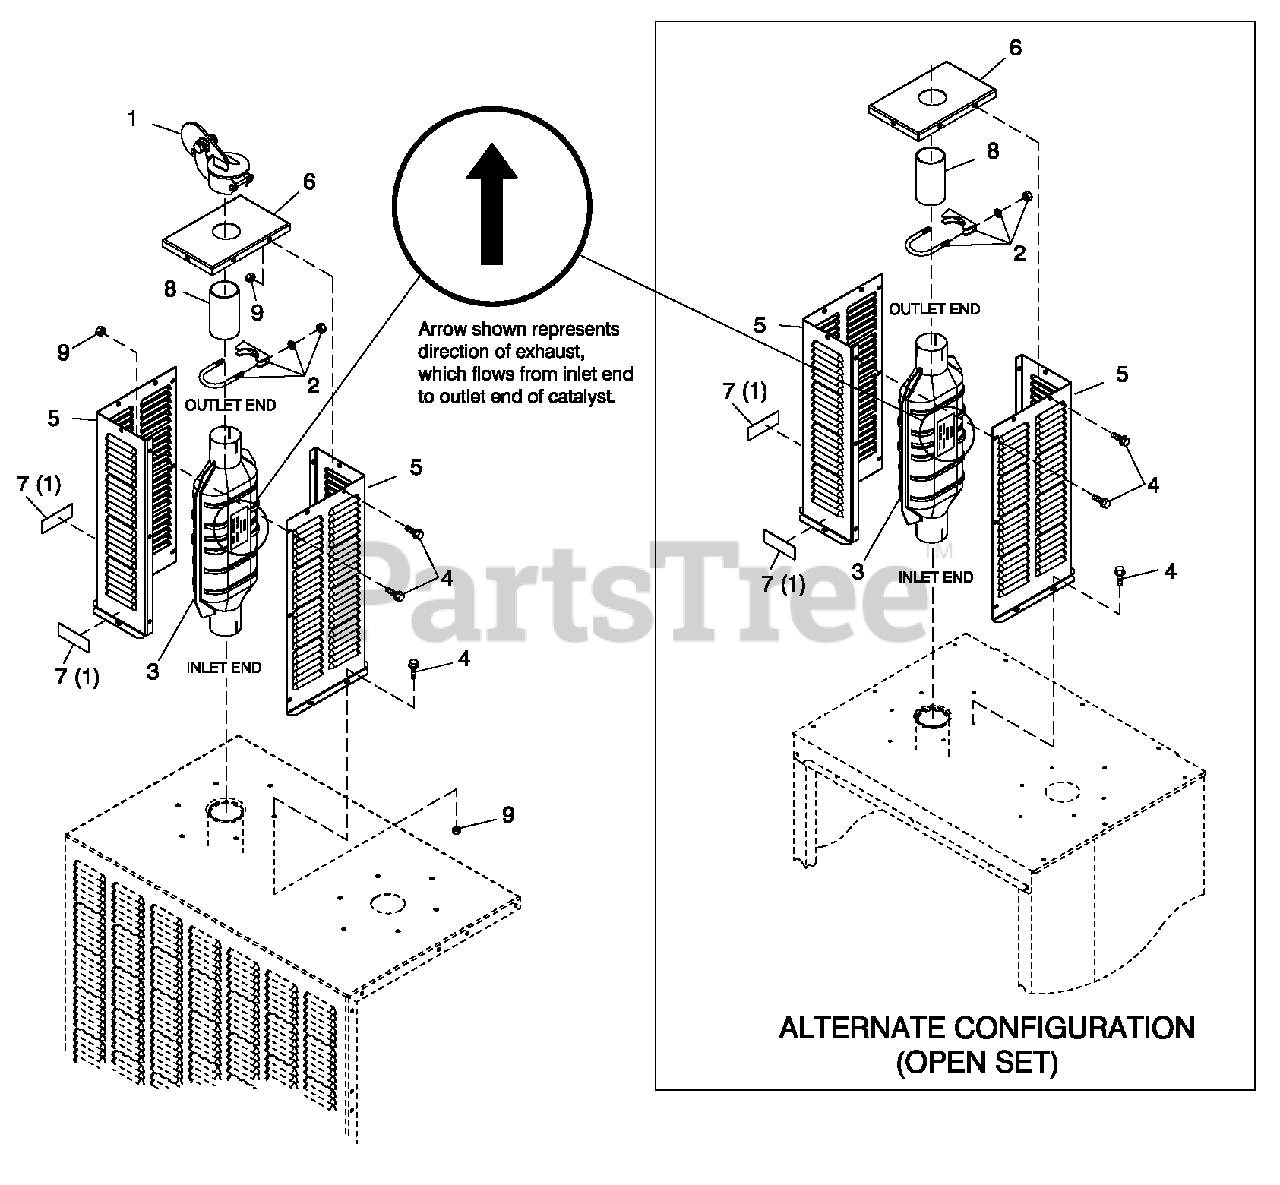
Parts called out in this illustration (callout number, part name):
1	RAIN CAP 2-1/2" AL
2	BOLT U 3/8-16X2.62
3	CATALYST 3-WAY
4	SCREW THF M6-1X16 N WA Z/JS
5	HEAT SHIELD EXHAUST STACK
6	CAP HEAT SHIELD EXHAUST STACK
7	DECAL WARNING HOT SURFACES BI
8	EMISS EXH OUTLET PIPE CPL
9	NUT HEX LOCK M6-1.0 SS NY INS
